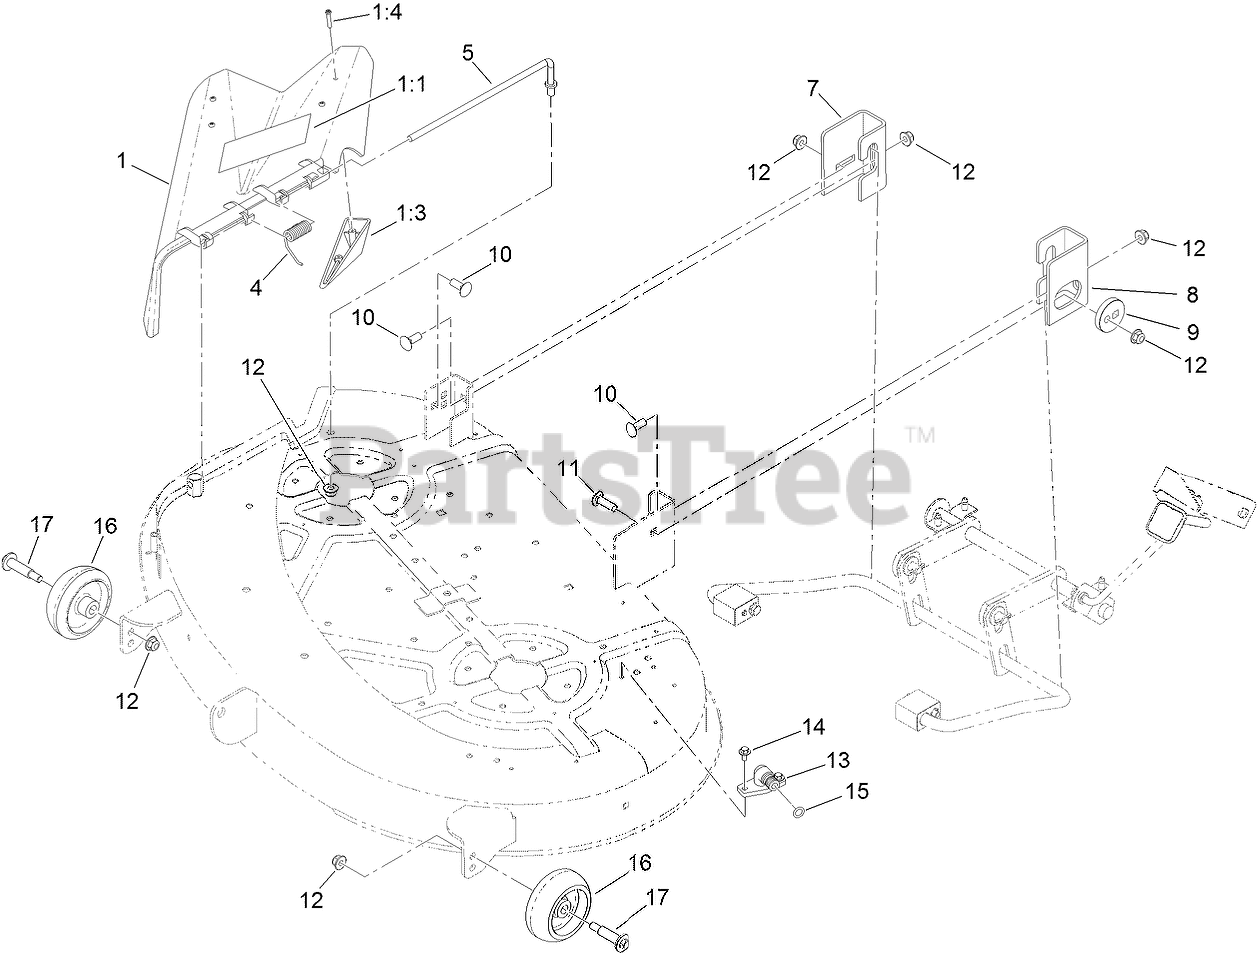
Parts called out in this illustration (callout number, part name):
1	DEFLECTOR ASM
1:1	DECAL-DANGER
1:3	KICKER
1:4	SCREW-PPH
4	SPRING-TORSION
5	ROD-PIVOT
7	BRACKET-HANGER, RIGHT REAR
8	BRACKET-HANGER, LEFT REAR
9	ECCENTRIC
10	BOLT-CARR
11	SCREW-CARR
12	NUT-HF, NI
13	FITTING-WASHOUT
14	SCREW-HHFTF
15	O-RING
16	WHEEL-GAGE
17	SCREW-SHOULDER, HWH
